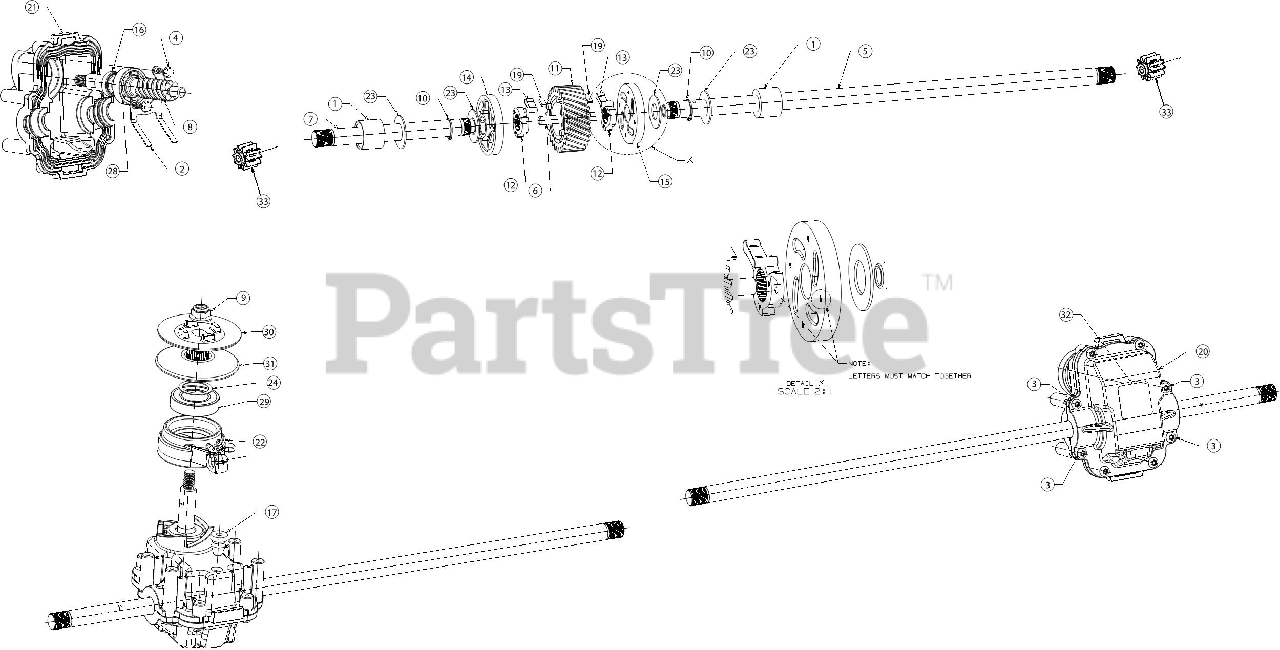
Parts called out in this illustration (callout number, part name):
3	SCREW .159 X .610
4	SCREW .159 X .43
9	FLANGE LOCK NUT 5/16-18
10	SNAP RING FOR .500
23	FLAT WASHER .508X1.000X.040
28	BALL BEARING
30	UPPER TRANSMISSION PULLEY
31	LOWER TRANSMISSION PULLEY
32	TRANSMISSION COVER
33	SPUR GEAR 9T
